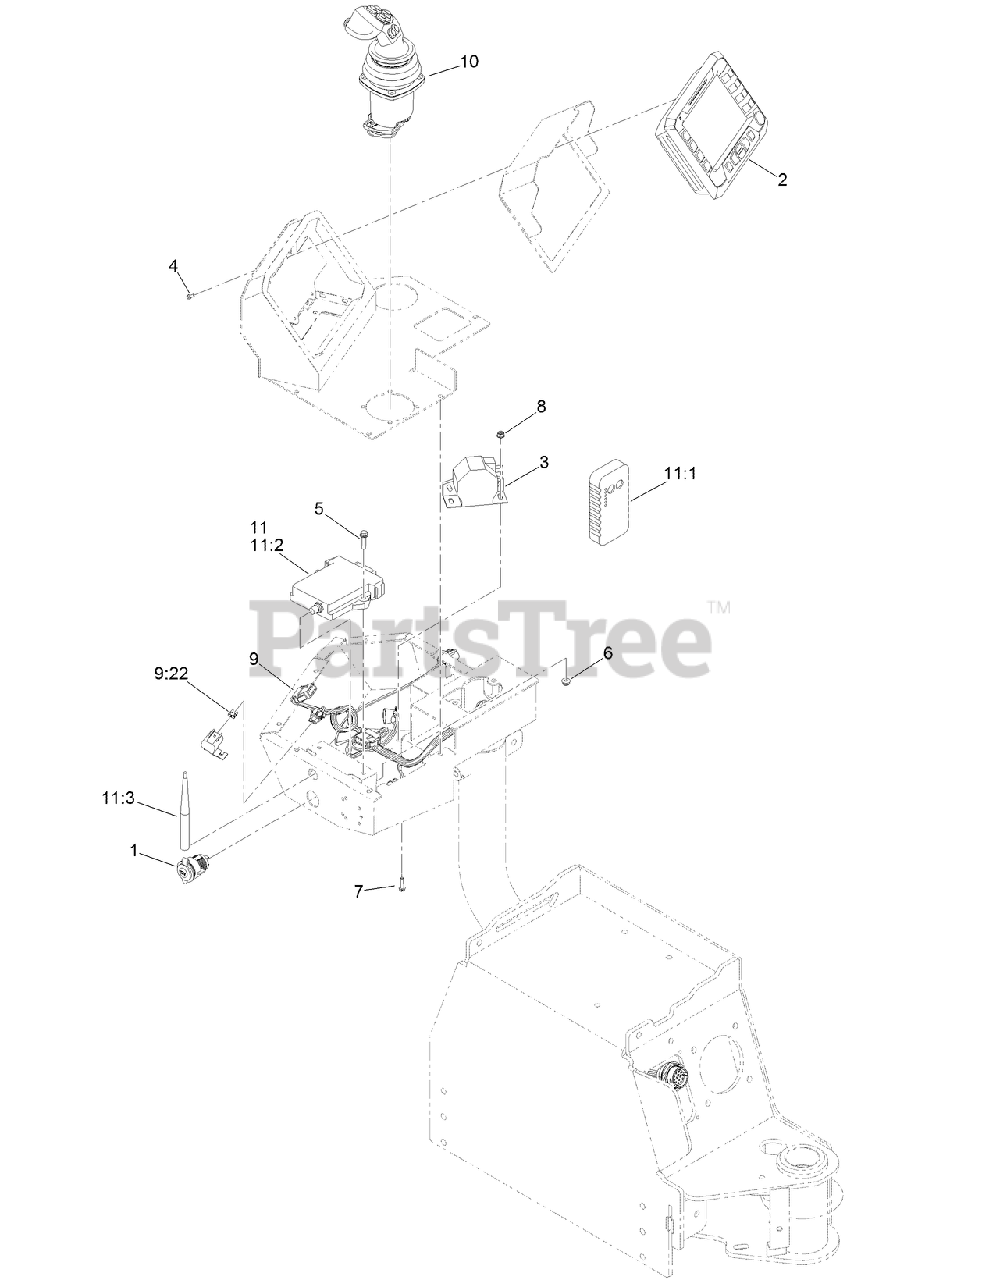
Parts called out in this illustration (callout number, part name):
1	RECEPTACLE-12V
2	DISPLAY
3	ALARM-BACKUP
4	SCREW-HH
5	SCREW-HHF
6	NUT-HF
7	SCREW-HWH
8	NUT-HF
9	HARNESS-WIRE, RIGHT CONSOLE
9:22	FUSE-MINI BLADE, 5 AMP
10	JOYSTICK-RH
11	LONG RANGE EXIT SIDE LOCKOUT KIT
11:1	HANDHELD-RANGE, LONG
11:2	BASE UNIT-RANGE, LONG
11:3	ANTENNA-LOCKOUT
